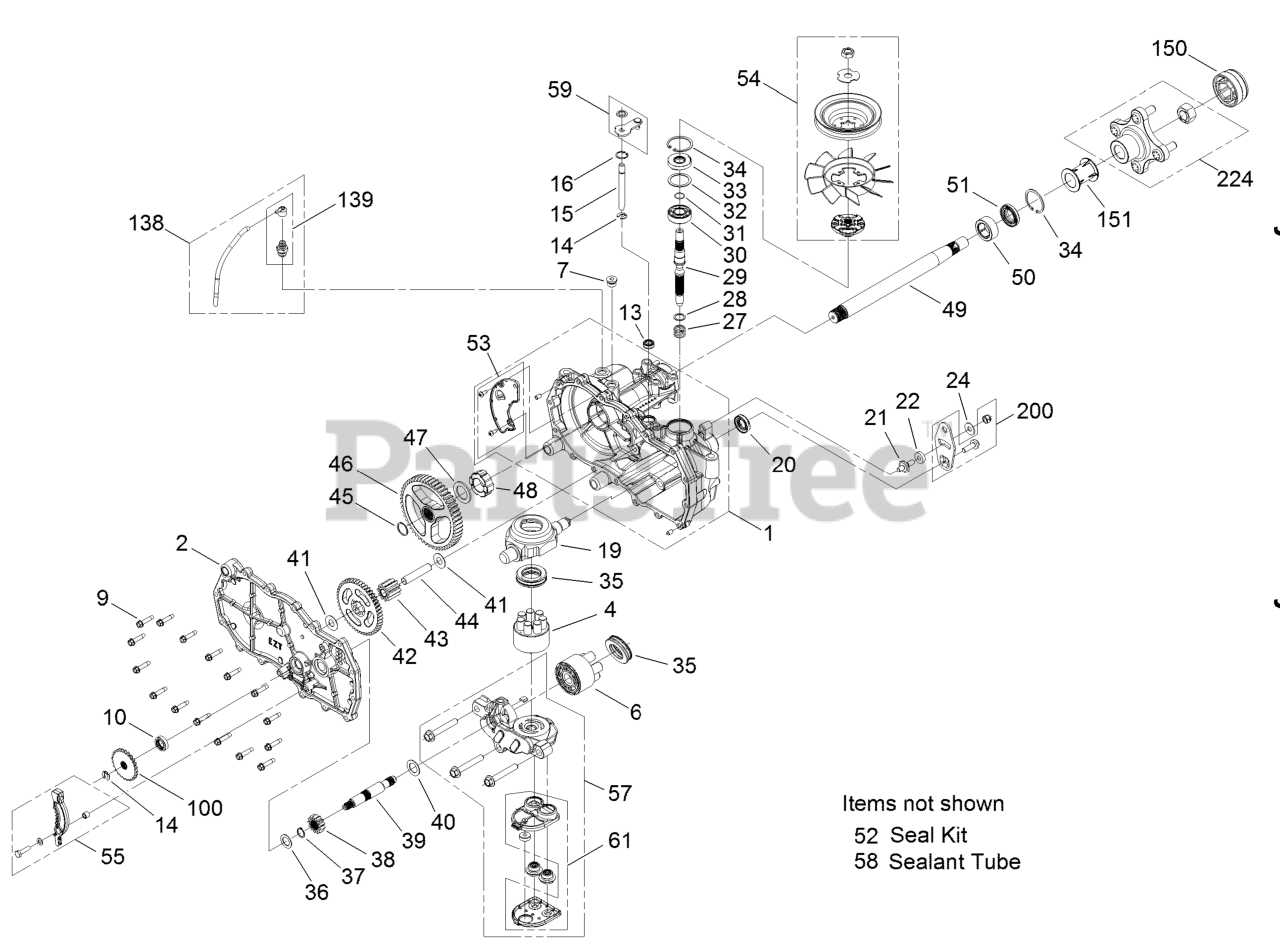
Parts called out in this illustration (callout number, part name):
1	MAIN HOUSING ASM
2	SIDE ASM
4	PUMP BLOCK ASM
6	CYLINDER BLOCK KIT
7	PLUG-THREAD, STRAIGHT
9	SCREW-HHF
10	SEAL-OIL
13	SEAL-LIP
14	RING-RETAINING, EXTERNAL
15	ROD-BYPASS
16	RING-RETAINING, INTERNAL
19	SWASHPLATE-TRUNNION
20	SEAL-LIP
22	PUCK-FRICTION
29	SHAFT-INPUT
30	BEARING-BALL
31	RING-RETAINING
33	SEAL-LIP
34	RING-RETAINING
35	BEARING-THRUST
36	WASHER-FLAT
37	RING-RETAINING
38	GEAR-PINNION, 13T
39	SHAFT-MOTOR
41	Washer
42	GEAR-10T/48T
43	GEAR-JACKSHAFT, 10T
44	PIN-JACKSHAFT
45	RING-SPIRAL, RETAINING
46	GEAR-52T, BULL
48	BEARING-SLEEVE
49	SHAFT-AXLE
50	BUSHING-AXLE
51	SEAL-LIP
53	EXPANSION PLATE KIT
54	Fan Pulley Kit
55	BRAKE ARM KIT
57	CENTER SECTION FILTER KIT
59	BYPASS ARM KIT
61	FILTER KIT
100	DISC-BRAKE, COG
138	BREATHER KIT
139	BREATHER ASM
150	COVER-NUT, AXLE
151	TUBE-AXLE
200	CONTROL ARM KIT
